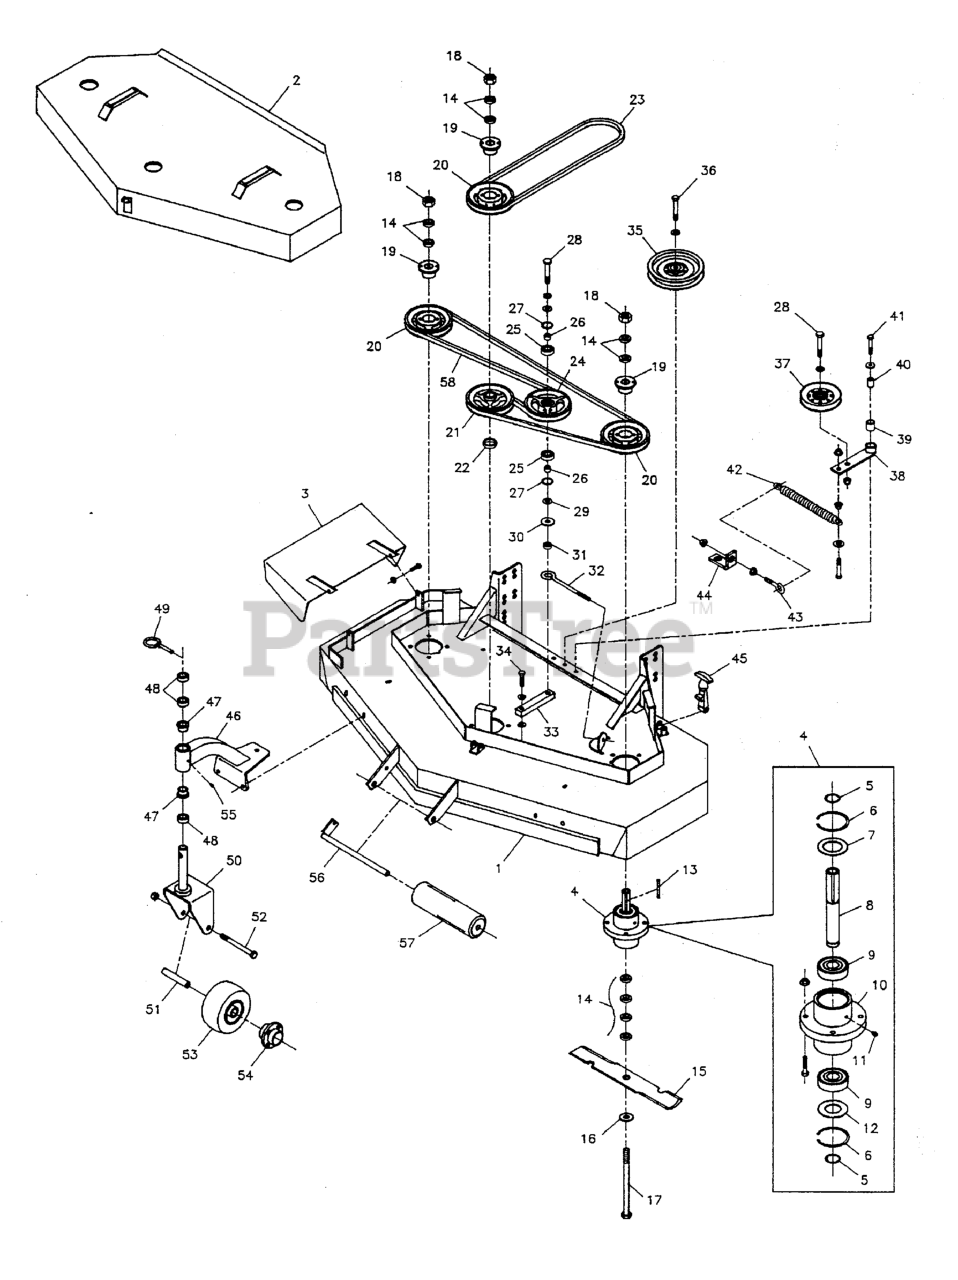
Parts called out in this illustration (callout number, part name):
1	61" MOWER HOUSING ASSEMBLY
2	61" SPINDLE COVER
3	CHUTE, DISCHARGE WELDMENT
4	SPINDLE ASSEMBLY, Complete
5	SNAP RING, External
6	SNAP RING, Internal
7	SPINDLE WASHER, Top
8	SPINDLE SHAFT
9	BEARING
10	SPINDLE HOUSING
11	GREASE FITTING
12	SPINDLE WASHER, Bottom
13	KEY, 1/4 SQ. X 2-1/2
14	SPACER, .63 x 1.06 x .23
15	MOWER BLADE, 21"
16	WASHER, 5/8" USS
17	BOLT, 5/8-11 x 9-1/2
18	NUT, 5/8-11 Hex
19	BUSHING, Tapered Hub
20	PULLEY, Spindle
20	PULLEY, Split Steel
21	SPINDLE PULLEY
21	PULLEY, Split Steel
22	SPACER, 1.00 X 1.25 X .25
23	BELT, Deck Drive
23	Deck Drive Belt
24	IDLER PULLEY, Complete
24	PULLEY, Idler
25	BEARING, BALL 11/16X1-9/16X15/32
26	INSERT, Bearing
27	SNAP RING, Internal
28	BOLT, 1/2-20 X 2-1/4 GD5 CZ
28	BOLT, 1/2-20 X 1-3/4" GD8 CZ
29	WASHER, 1/2 SAE
30	WASHER, 1/2" USS
31	SPACER, .52 X 1.00 X .38
32	EYEBOLT, 3/8" x 8"
32	J-BOLT
33	ARM, Idler
33	IDLER ARM
34	BOLT, 7/16-20 X 1-3/4" GD.5
35	PULLEY, Backside Idler
36	BOLT, 1/2-20 X 2-1/2" GD5 CZ
37	PULLEY, V-Idler
38	IDLER ARM, Complete
39	BUSHING, Brass
40	SPACER, .32 x .75 x 1.06
41	BOLT, 5/16-18 x 1-3/4
42	SPRING, Extension
43	EYEBOLT
44	SPRING ANCHOR
45	RUBBER LATCH
46	CASTER MOUNT, Complete
47	BUSHING, FLANGE
48	SPACER, 1.02 x 1.56 x .50
49	PIN, Lynch
50	YOKE, Caster
51	AXLE, Caster Wheel
52	BOLT, 1/2-13 x 5-1/2
53	WHEEL & TIRE ASSEMBLY, White, 9 x 3.5 x 4, Complete
54	4 BOLT HUB W/ BEARING
55	GREASE FITTING
57	ROLLER
58	BELT, Blade Spindle
